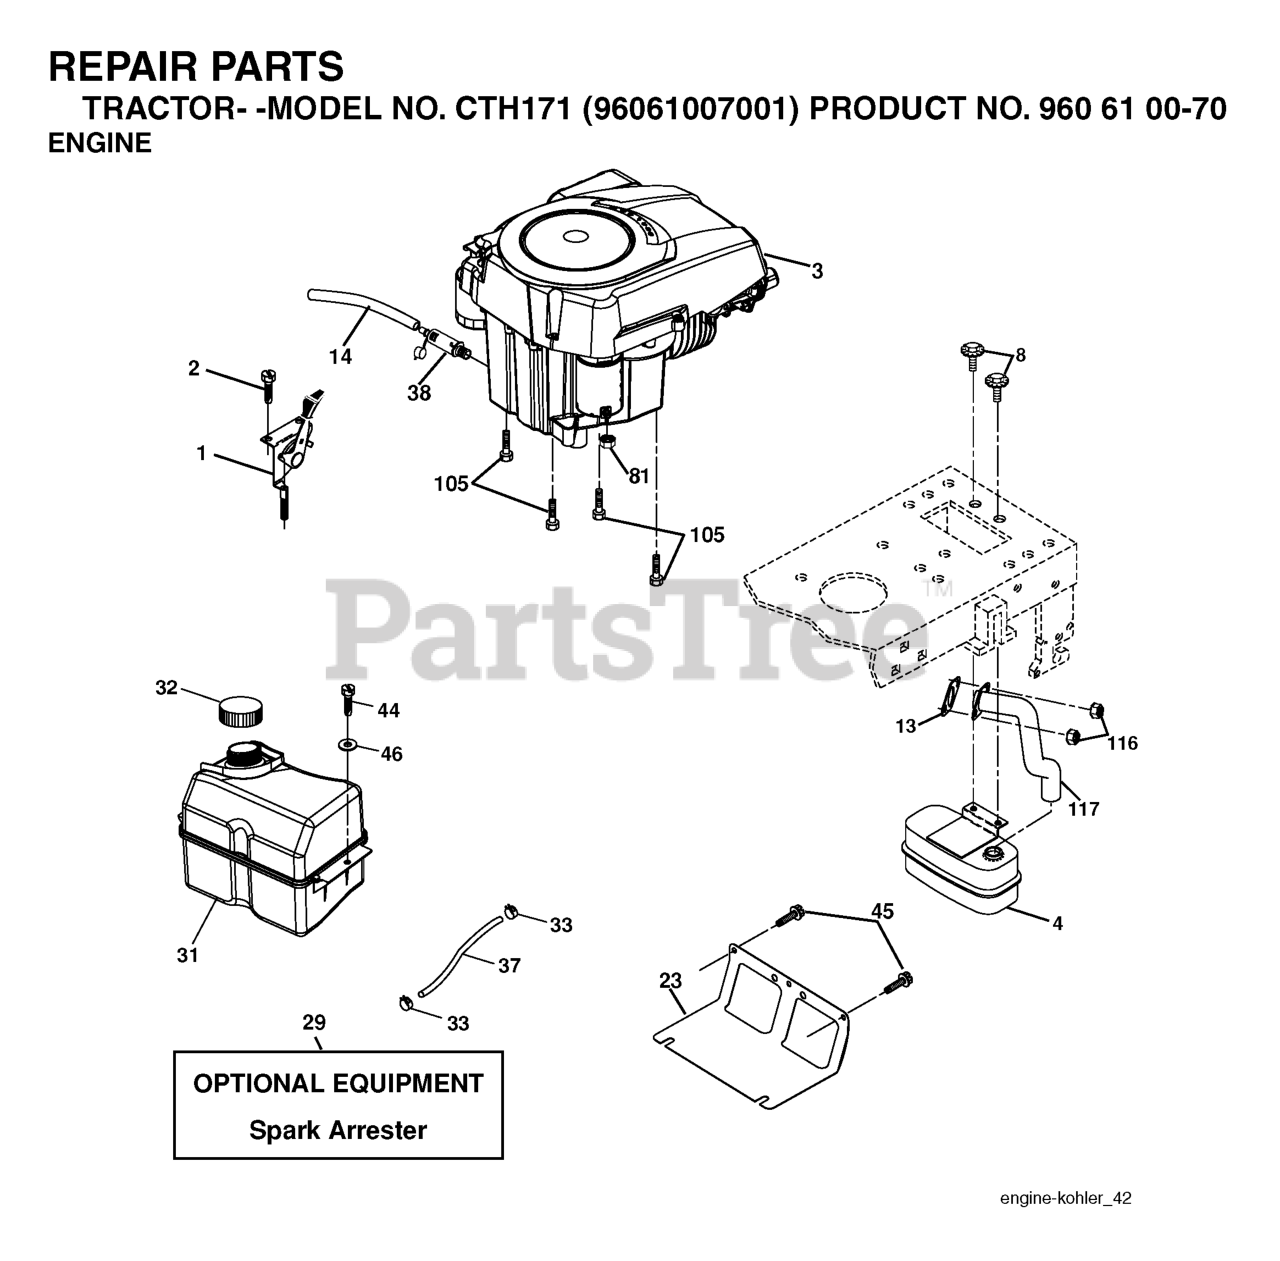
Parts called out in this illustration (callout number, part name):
1	CONTROL.THROTTLE.LT/YT
2	SCREW
4	MUFFLER.SINGLE.CYL.KOHL/B&S
8	BOLT.5/16-18UNCX3/4 W/SEMS.BLK
13	GASKET.EXHAUST.KOHLER
14	TUBE, DRAIN OIL ASM.
23	SHIELD.BROWNING.DBR.GUARD
29	KIT.SPARK ARRESTOR 794945 B&S
31	TANK FUEL
32	FUEL CAP
33	HOSE CLAMP
37	LINE.FUEL.20
38	PLUG DRAIN OIL EASY
44	SCREW HEXWSHR 1/4-20X3/4
45	SCREW, 3/8-16X3/4
81	NUT
105	SCREW 3/8-16X1
116	NUT.HEX.FLANGE.TOPLOCK
117	RP.TUBE.EXHAUST.KOHL.COURAGE
